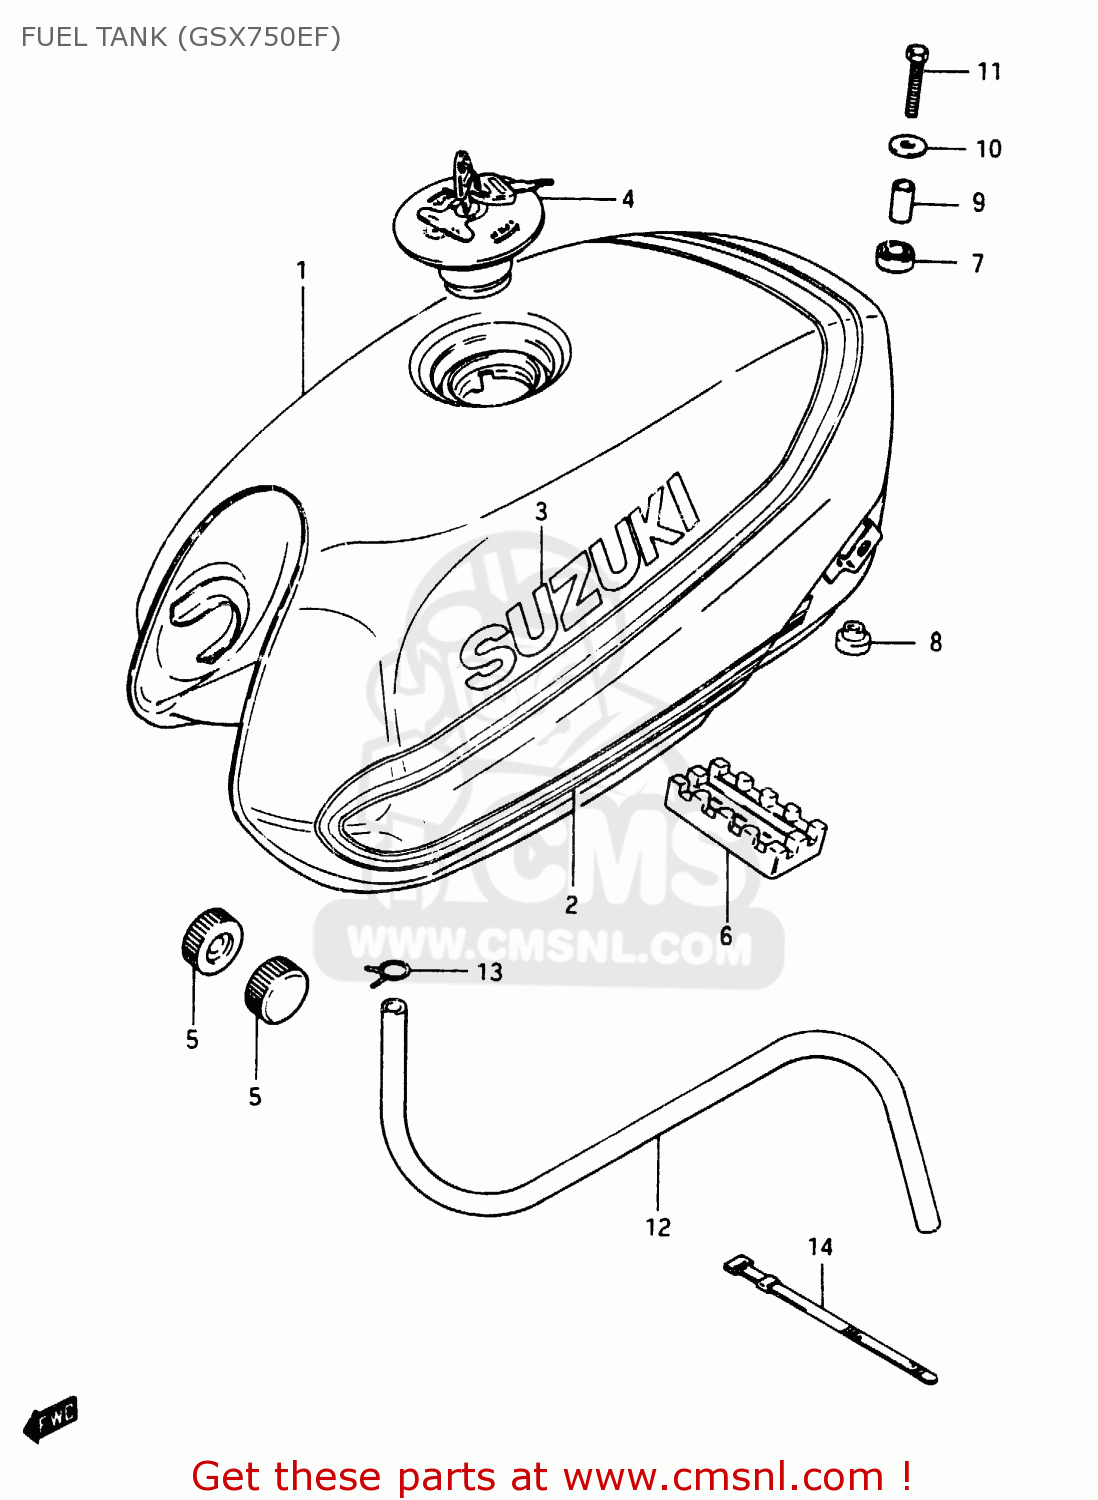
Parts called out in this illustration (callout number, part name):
1	TANK, FUEL
2	TAPE SET, FUEL TANK
3	EMBLEM
4	CAP, FILLER
5	CUSHION
6	CUSHION,FUEL TANK CTR
7	CUSHION
8	CUSHION
9	SPACER
10	WASHER (6.5X24X1.6)
11	BOLT
12	HOSE,FUEL
13	CLIP
14	CLIP(ID:16)
